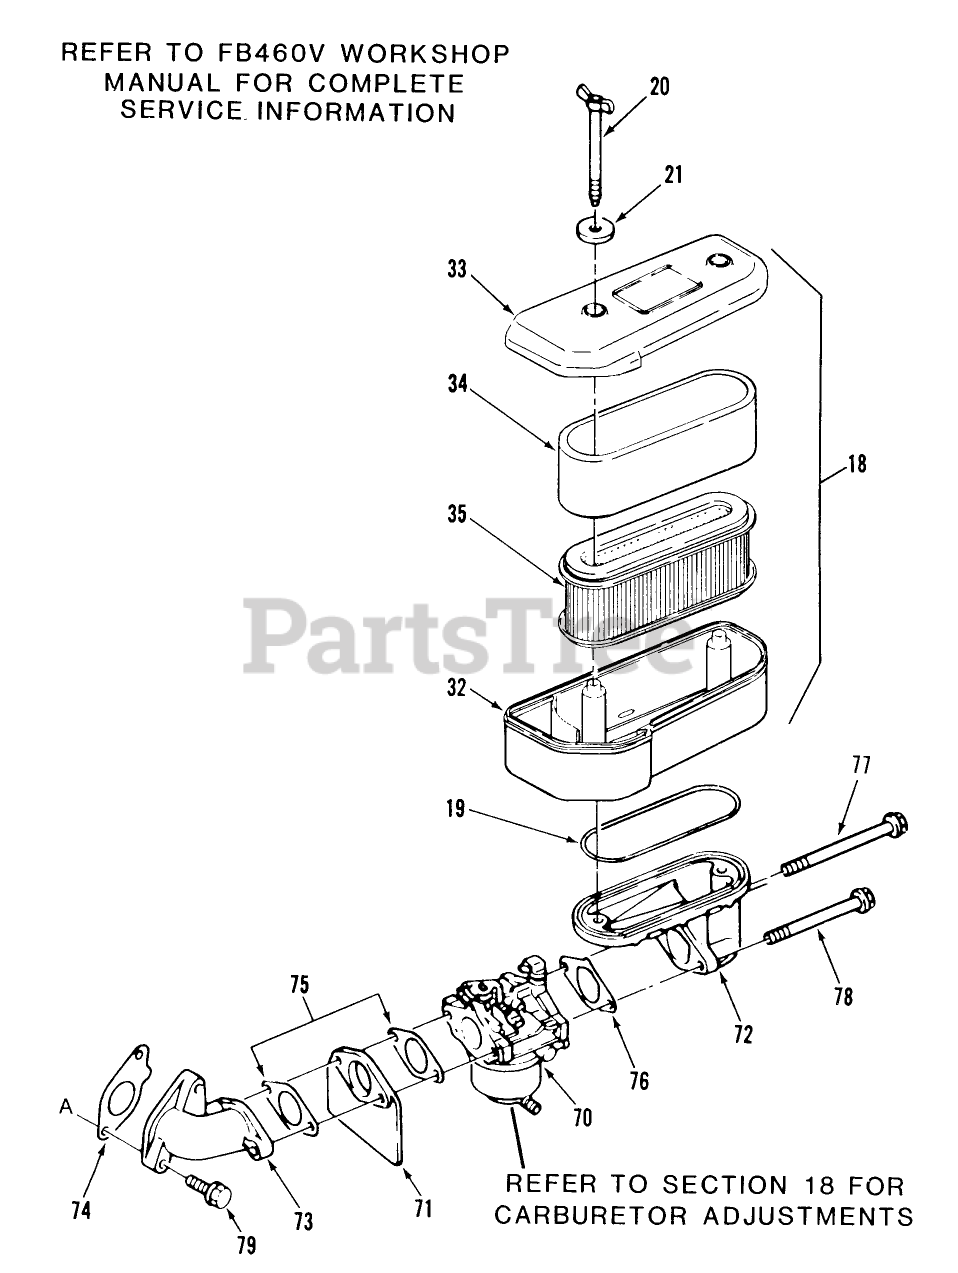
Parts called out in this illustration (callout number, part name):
18	Air Filter Assy (includes items 32, 33, 34 35)
32	Air Filter Case
33	CAP-Air Filter
34	Element
35	Element
70	Carburetor Assy-see section 9-6 for parts breakdown
71	Insulator
72	Pipe-Intake
73	Pipe-Intake
79	Bolt 8x25
